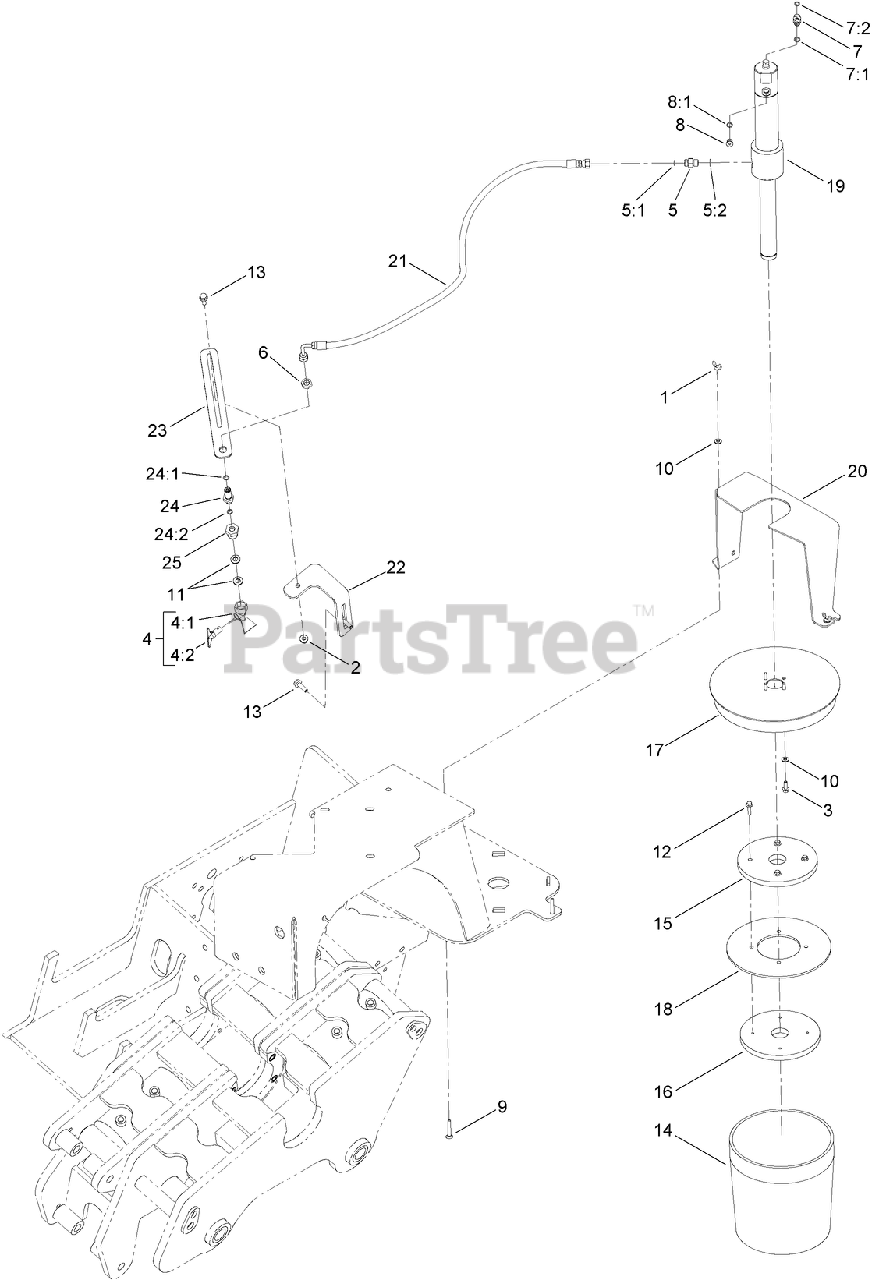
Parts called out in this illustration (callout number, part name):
1	WINGNUT
2	NUT-LOCK, HHF
3	SCREW-HHF
4	SPRAY NOZZLE ASM
4:1	NOZZLE-SPRAY, AIRLESS
4:2	ORIFICE INSERT ASM
5	FITTING-STRAIGHT
5:1	O-RING
5:2	O-RING
6	NUT-LOCK
7	FITTING-STRAIGHT
7:1	O-RING
7:2	O-RING
8	PLUG ASM
8:1	O-RING
9	SCREW-CARR
10	WASHER-FLAT
11	WASHER-FLAT
12	SCREW-HHF
13	SCREW-HHF
14	COMPOUND-THREAD
17	COVER-APPLICATOR, LUBE
18	SEAL-RUBBER, FOLLOWER
19	HYD GREASE PUMP ASM
20	TIEDOWN-COVER, GREASE
21	HYD HOSE ASM
22	BRACKET-MOUNT, NOZZLE
23	MOUNT-SLIDE, NOZZLE
24	FITTING-STRAIGHT
24:1	O-RING
24:2	O-RING
25	REDUCER-STRAIGHT, THREADED
